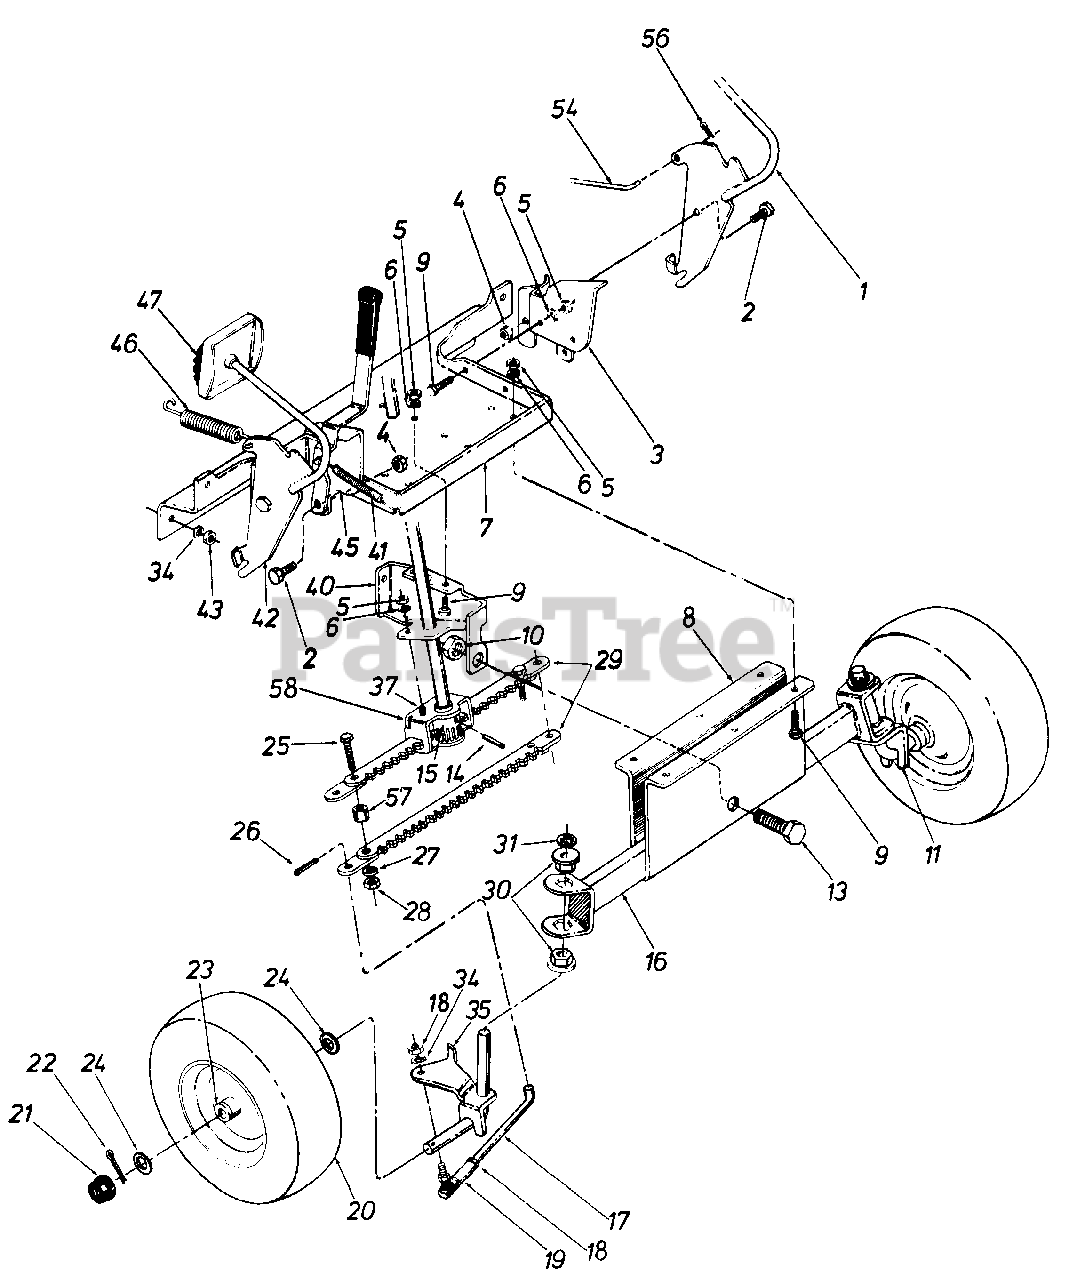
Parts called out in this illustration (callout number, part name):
1	Foot Pedal Ass'y.
2	Shld. Scr. .500" Dia. x .170
3	L.H. Brake Pivot Brkt.
4	Hex Center L-Nut 3/8-16 Thd.
5	Hex Nut 5/16-18 Thd.
6	Spring L-Wash. 5/16" Scr.
7	Front Frame
8	Front Pivot Brkt.
9	Hex Sems Scr. 5/16-18 x .75
10	Hex Center L-Nut 5/8-18 Thd.
11	Front Axle Ass'y. L.H.
13	Hex Scr. 5/8-18 x 1.31 Lg.
14	Spring Pin 3/16 Dia. x 1.50" Lg.
15	Spur Gear 12 Tooth
16	Pivot Bar Ass'y.
18	Hex Jam Nut 3/8-24 Thd.
19	Ball Joint
20	Front Wheel Ass'y. - Comp.
21	Hub Cap
22	Cotter Pin 1/8" x 1-1/4" Lg.
23	Flange Bearing
24	Flat Wash. .625 I.D.
25	Hex Scr. 1/4-20 x 1.50
26	Cotter Pin 3/32 Dia. x .75 Lg.
27	Spring L-Wash. 1/4 Scr.
28	Hex Nut 1/4-20 Thd.
29	Steering Rack
30	Flange Bearing
31	Push Nut .625 Shaft
34	Spring L-Wash. 3/8 Scr.
35	Front Axle Ass'y. R.H.
37	Cross Recess Truss Hd. Scr. 5/16-18 x .75" Lg.
40	Steering Box Support
41	Spring
42	Foot Pedal Ass'y.
43	Hex Nut 3/8-16 Thd.
45	R.H. Pivot Brkt.
46	Brake Tension Spring
47	Pad - Vinyl-Brake
54	Clutch Rod
56	Cotterpin 3/32 Dia. x .75 Lg.
58	Steering Housing
